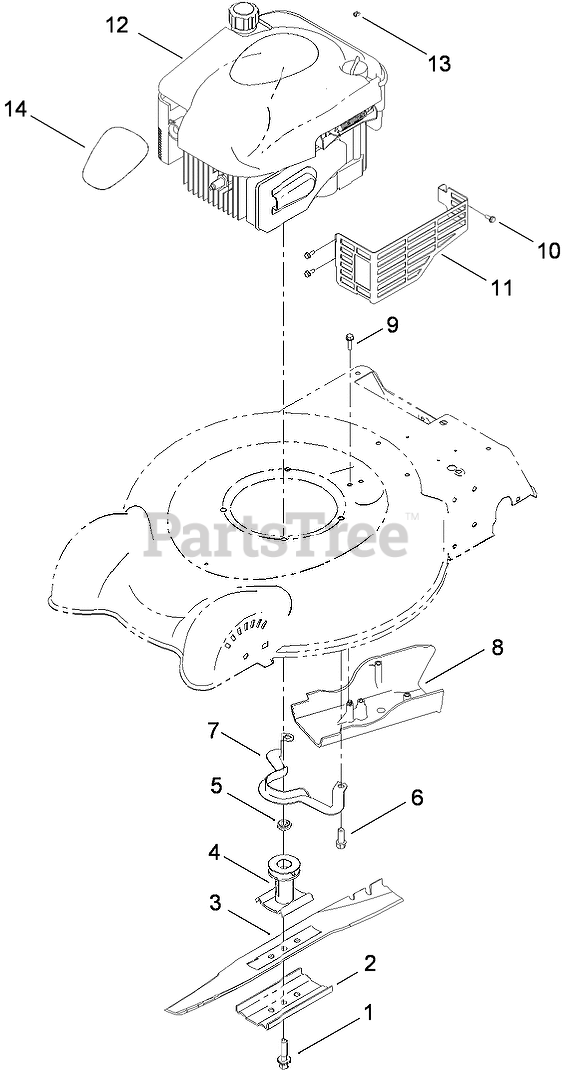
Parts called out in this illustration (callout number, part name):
1	BOLT-BLADE
2	SUPPORT-BLADE
3	BLADE-20 INCH
4	DRIVER-BLADE
5	Spacer-Driver
6	SCREW-TAPTITE
7	Guide-Belt
8	COVER-BELT
9	SCREW-HWH
10	SCREW-TAPTITE
11	SHIELD-MUFFLER
13	STOP-ROPE
14	DECAL-ENGINE
